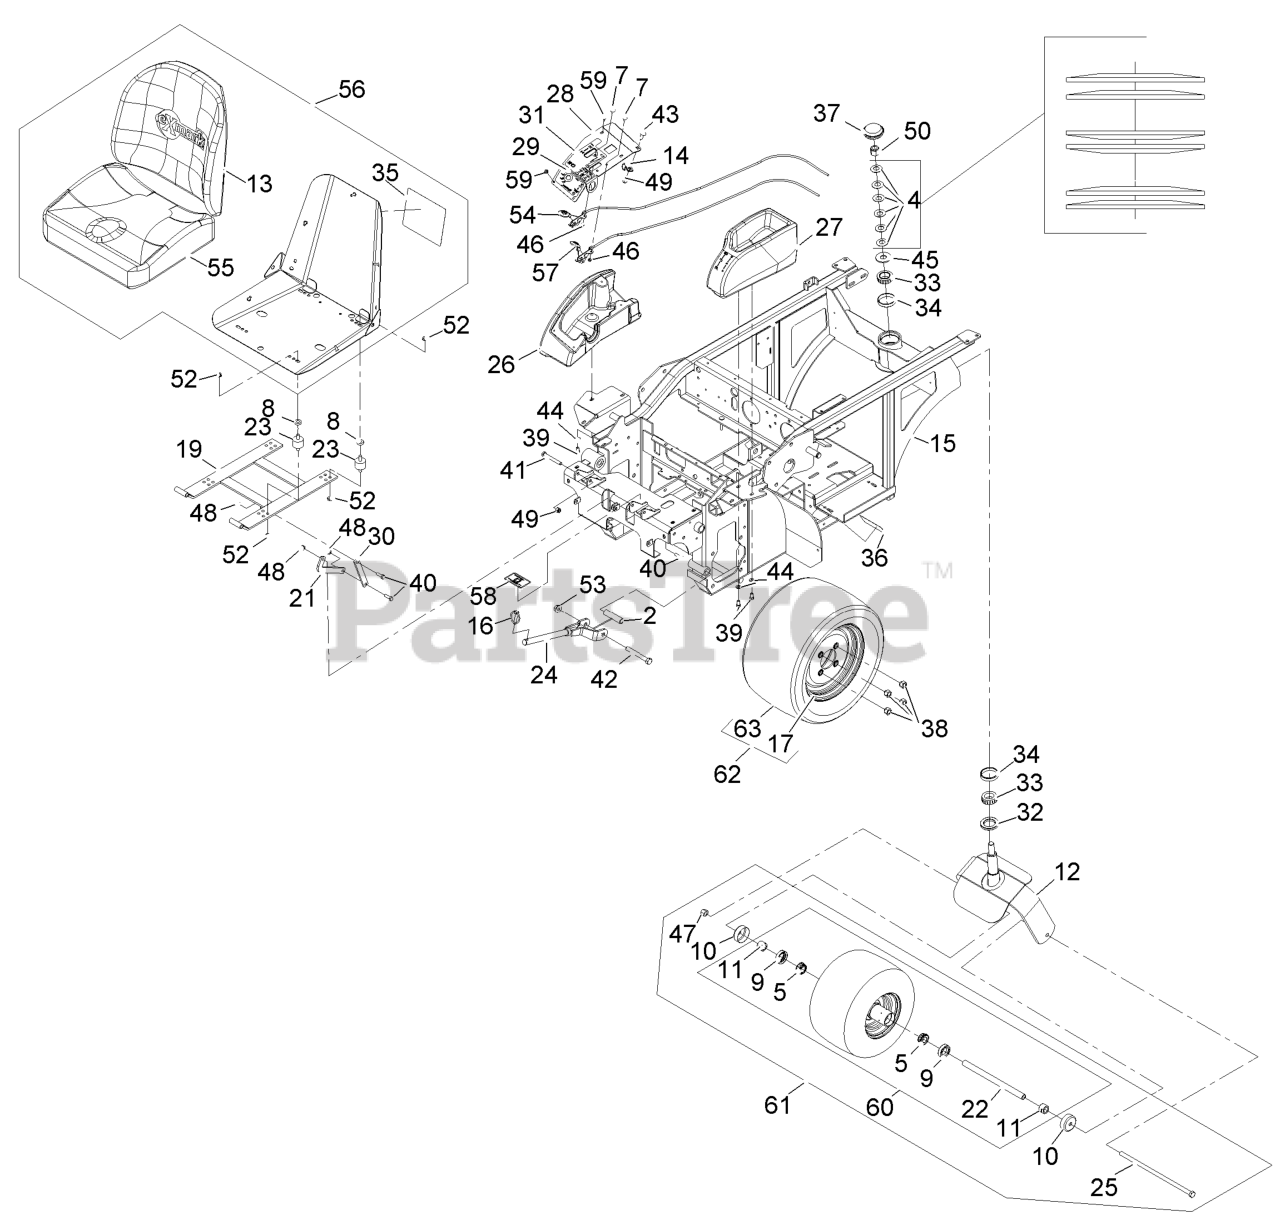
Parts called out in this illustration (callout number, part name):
2	SPACER-WHEEL, SHORT
4	WASHER-BELLVILLE
5	BEARING-CONE, TAPERED ROLLER
7	BOLT-CARR
8	SPACER
9	SEAL-CASTER
10	GUARD-SEAL
11	SPACER-NUT
12	FORK-REAR CASTER
13	CUSHION,SEAT BACK
14	CLIP-LOOM
15	ASM-FRAME W/DECALS AND BU
16	PIN-LYNCH
17	ASM,WHEEL
19	FRAME-SEAT
21	LINK-SEAT STOP, LOWER
23	MOUNT-VIBRATION, RUBBER
25	SCREW-HH
28	ASM-INTRUMENT PANEL W/DEC
29	DECAL,IGNITION/SPEED CONT
30	LINK-SEAT
31	DECAL,INSTRUMENT PANEL
32	SEAL-GREASE
33	BEARING-ROLLER, CONE TAPE
34	CUP-TAPERED, ROLLER BEARI
35	DECAL-SERVICE AID
36	DECAL,CLUTCH ADJUSTMENT
37	CAP-GREASE
38	NUT-LUG
39	SCREW-HH
40	SCREW-HH
41	SCREW-CARR
42	SCREW-HH
43	SCREW-CARR
44	WASHER-PLAIN
45	WASHER-FLAT
46	NUT-LOCK, NI
47	NUT-LOCK, NI
48	NUT-LOCK, NI
49	NUT-LOCK, NI
50	NUT-LOCK, NI
53	NUT-HHF
54	CABLE-CHOKE
55	ASM-SEAT BOTTOM CUSHION
57	CABLE-THROTTLE
58	DECAL,WHEEL MOTOR RELEASE
59	SCREW-PPH
60	ASM,WHEEL,TIRE & BRG SP
61	REAR CASTER WHEEL ASM
62	ASM,WHEEL & TIRE
